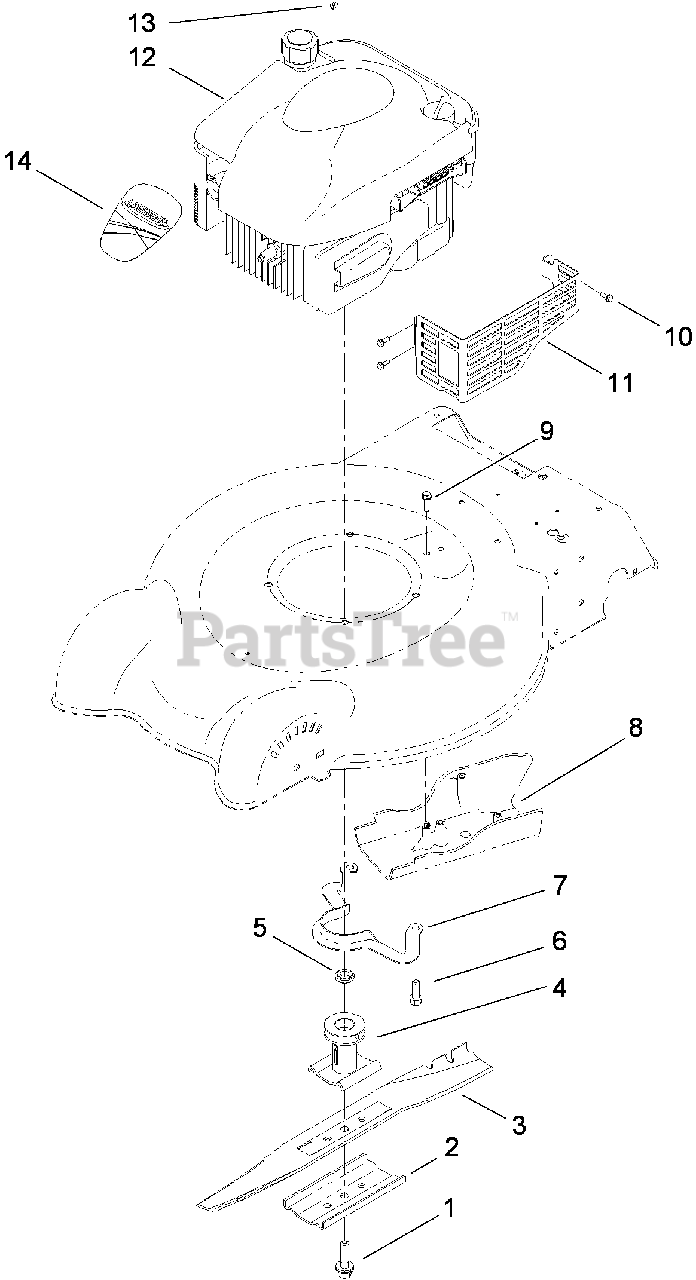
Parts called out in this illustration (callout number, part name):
1	BOLT-BLADE
2	SUPPORT-BLADE
3	BLADE-20 INCH
4	BLADE DRIVER ASM
5	Spacer-Driver
6	SCREW-TAPTITE
8	COVER-BELT
9	SCREW-HWH
10	SCREW-TAPTITE
11	SHIELD-MUFFLER
13	STOP-ROPE
14	DECAL-SHROUD
